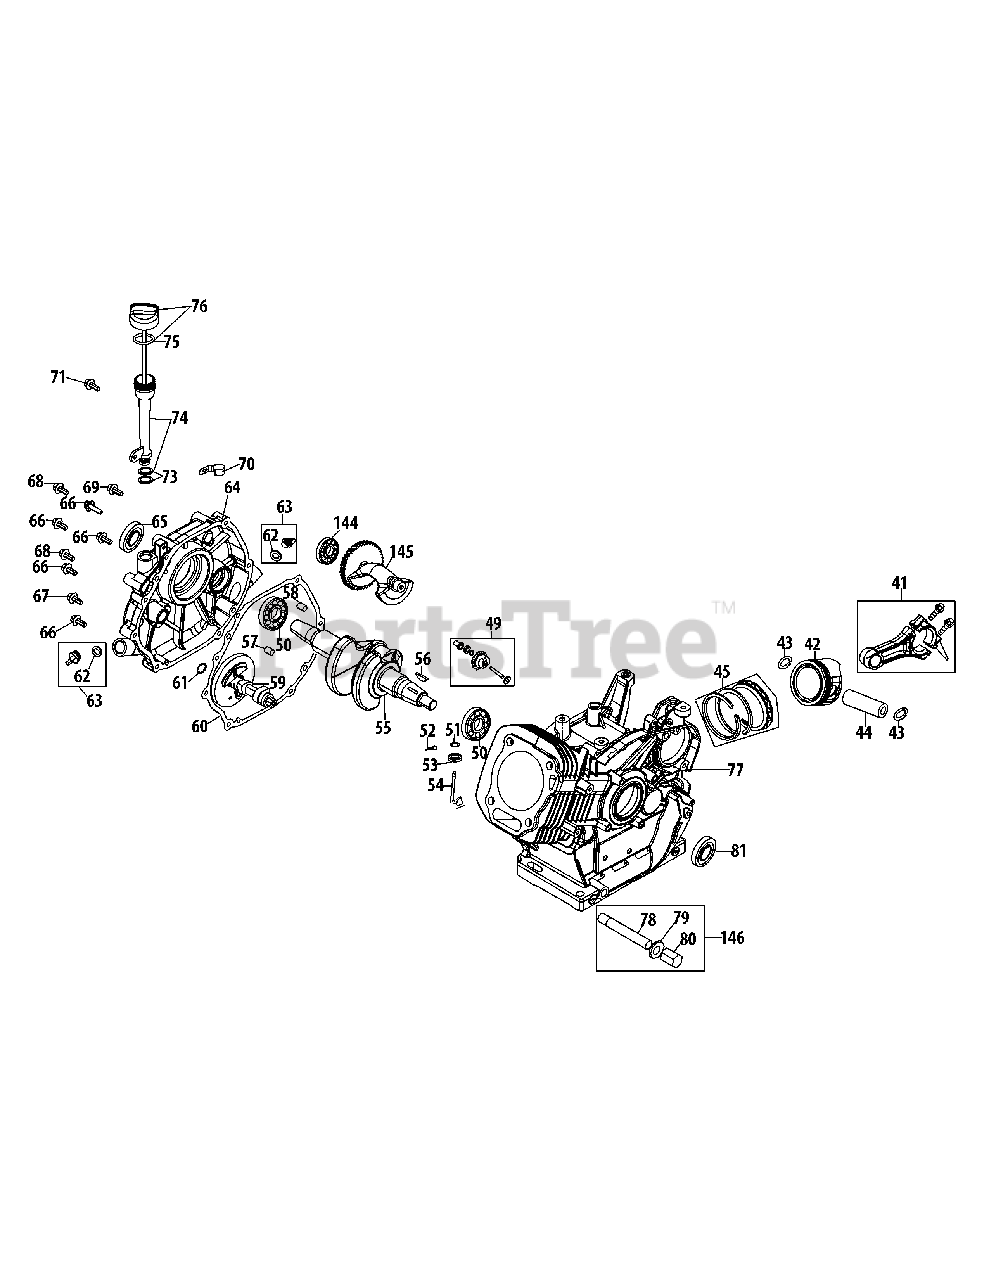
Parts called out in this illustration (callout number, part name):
41	Connecting Rod Assembly
42	Piston
43	Piston Pin Snap Ring
44	Piston Pin
45	Piston Ring Set
49	Governor Gear/Shaft Assembly
50	Radial Ball Bearing, 6202-P6
51	Washer 8×20×0.8
52	Cotter Pin
53	Governor Seal
54	Governor Arm Shaft
55	Crankshaft Kit
56	Woodruff Key
57	Dowel Pin 9×12
58	Dowel Pin 7×14
59	Camshaft Assy.
60	Crankcase Cover Gasket
61	Washer 16×24×0.5
62	O-Ring 16×3
63	Oil Filler Plug Assembly
64	Crankcase Cover Kit
65	Oil Seal, 30×46×8
66	Bolt M8×38
67	Bolt M8×45
68	Bolt M8×35
69	Bolt M6×16
70	Dipstick Clamp
71	Bolt M6×8
73	Oil Fill Tube O-Ring
74	Oil Fill Tube Assembly
75	Dipstick O-Ring
76	Dipstick Assembly
77	Crankcase Kit
78	Oil Drain Pipe Assy.
79	Washer 10×16×1.5
80	Oil Drain Plug
81	Oil Seal 35×52×7
144	Bearing, 6207-P6
145	Balance Shaft Assembly
146	Oil Drain Assembly
